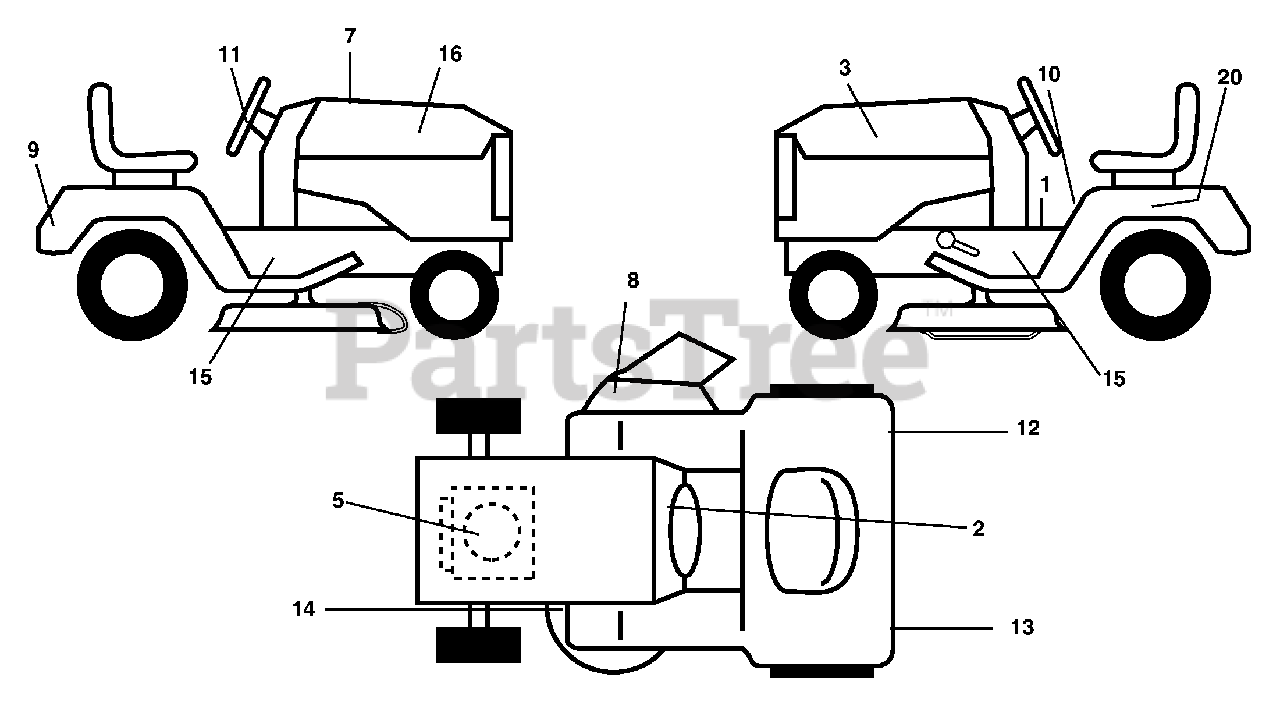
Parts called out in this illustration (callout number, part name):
1	Decal Oper
2	Decal Dash Insrt
3	Decal Hood LH
5	Decal Engine
7	Decal Replacement Parts
8	Decal Deck "B" 42"
9	Decal Fender Logo
10	Decal Fender Danger E/S
11	Decal Ins Strg Whl
12	Decal Fend Reflector Rh
13	Decal Fend Reflector Lh
14	Decal V-Belt Schematic
15	Decal Chassis
16	Decal Hood Rh
20	Decal Bat Dan/Psn
